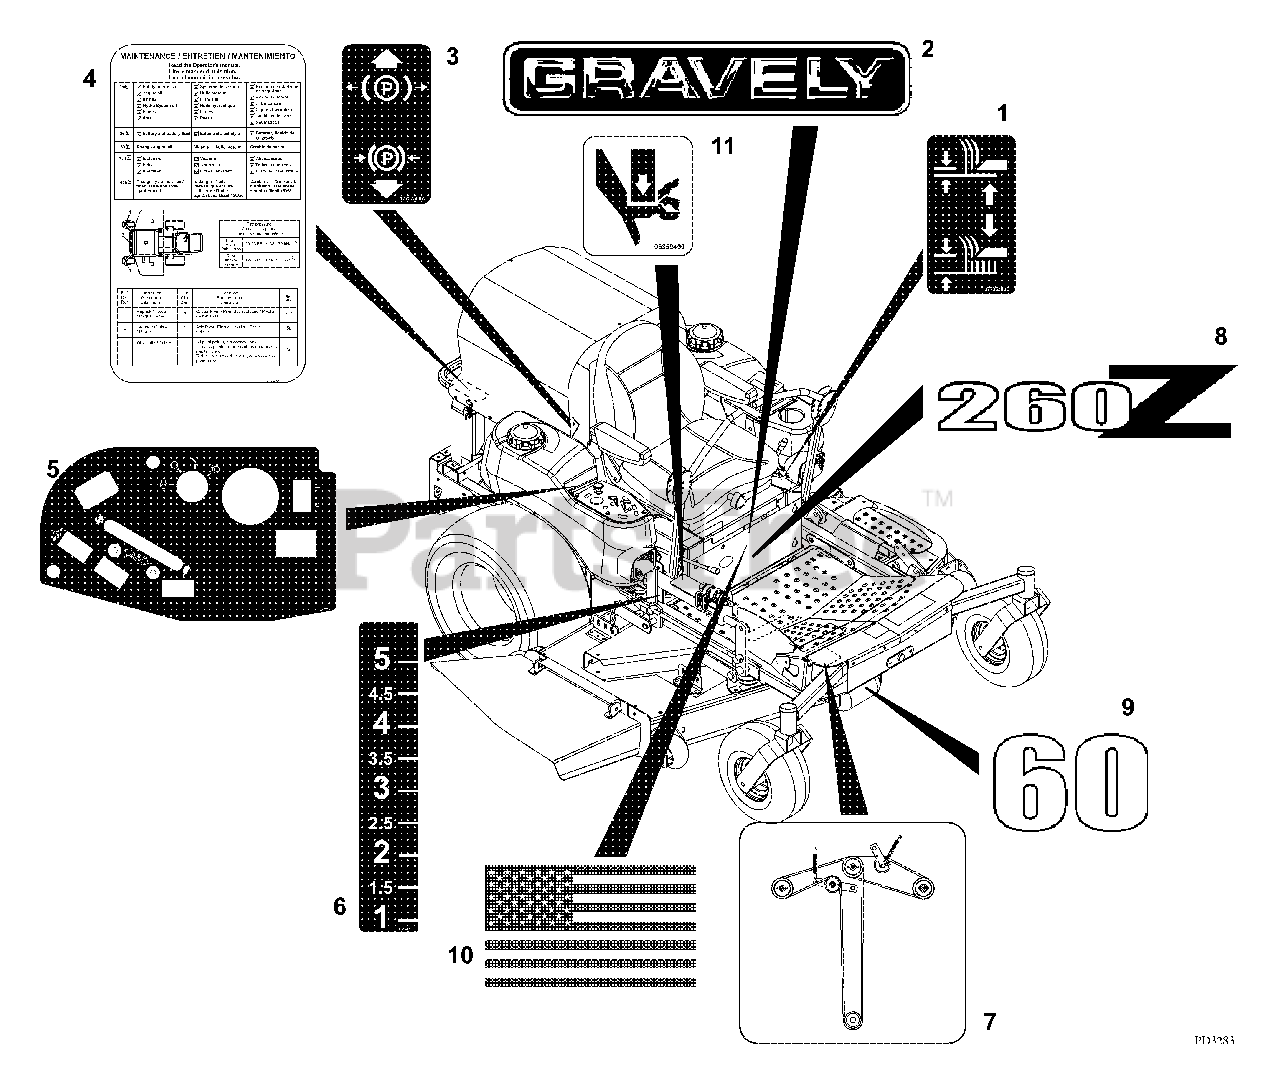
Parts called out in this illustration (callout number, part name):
1	Decal, Lift Lever
2	Decal, 15" Gravely Logo
3	Decal, Parking Brake Lever
4	Decal, Service Instructions
5	Decal, Diesel Control Panel (075, 076, 318, 319)
5	Decal, Control Panel (073, 074)
6	Decal, Height of Cut
7	Decal, Belt Diagram (073, 075, 318, 319)
7	Decal, Belt Diagram (074, 076)
8	Decal, PM-260Z (073, 075, 318, 319)
8	Decal, PM-272Z (074, 076)
9	Decal, 60 (073, 075, 318, 319)
9	Decal, 72 (074, 076)
10	Decal, American Flag
11	Decal, Pinch Point
